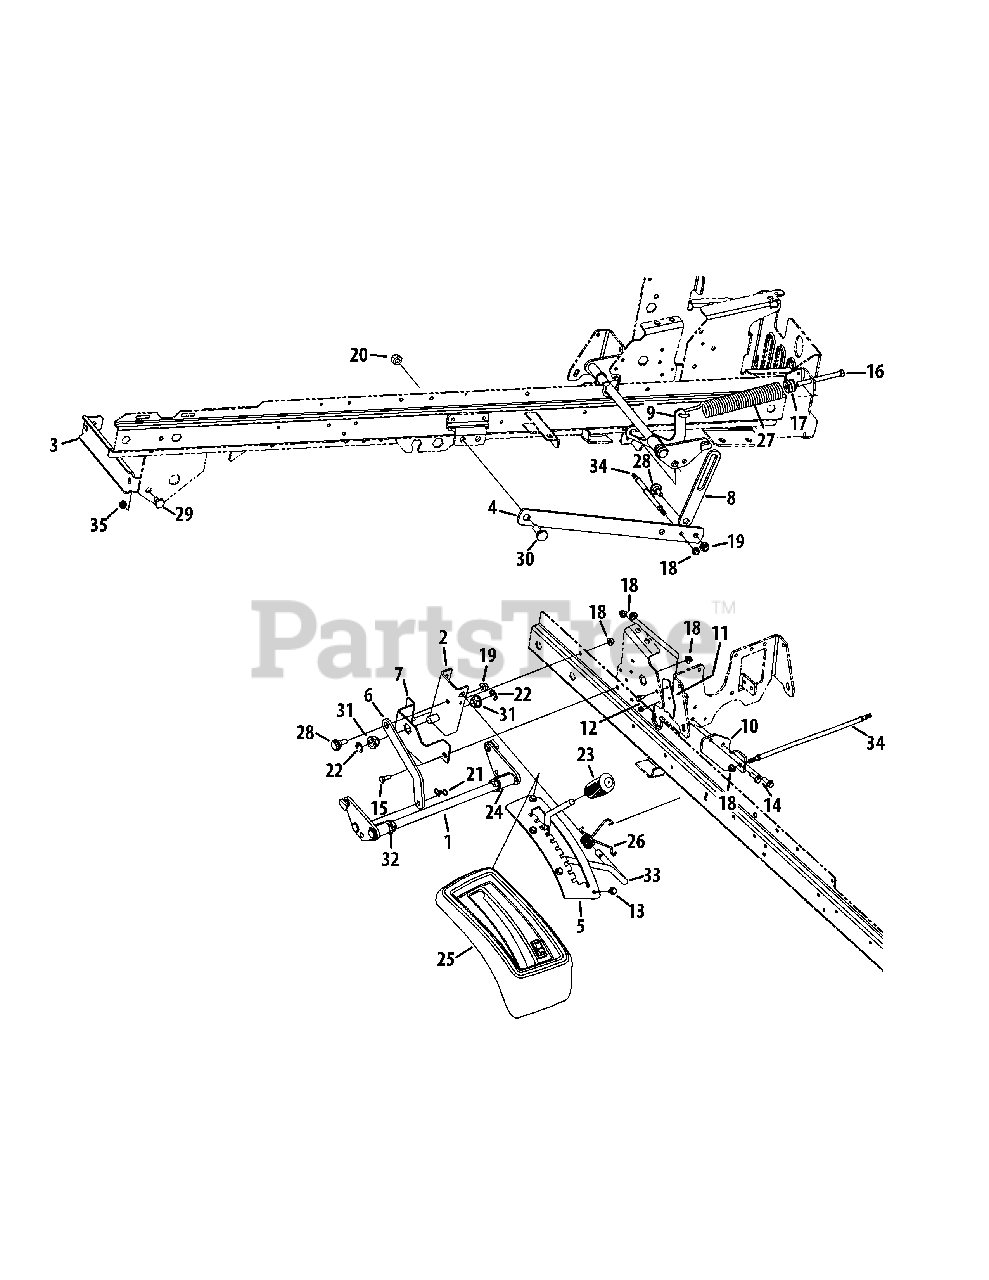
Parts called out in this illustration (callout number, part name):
1	Manual Lift Shaft Assembly
2	Manual Lift Lever Bracket Assembly
3	Front Hanger Bracket
5	Manual Lift Index Bracket
6	Manual Lift Link Plate
7	Manual Lift Lever Mount Bracket
8	Link Lift Plate
9	Extension Spring Plate
10	Sway Bar Mount Bracket
11	Bearing Stop Plate
12	Hex Washer Screw, 1/4-20 x .500
13	Hex Washer Screw, 5/16-18 x .625
14	Hex Washer Screw, 5/16-18 x .875
15	Hex Screw, 5/16-18 x .75
16	Hex Screw, 3/8-16 x 4.25
17	Spring Insert
18	Flange Lock Nut, 5/16-18
19	Flange Lock Nut, 3/8-16
20	Hex Lock Nut, 1/2-13
21	Bow-Tie Cotter Pin
22	E-Ring, .625
25	Lif Manual Cover
26	LH Torsion Spring
27	Extension Spring, 1.485 x 9.68
28	Shoulder Screw, 3/8-16 x .562 x .360
29	Shoulder Screw, 1/2 x .29
30	Shoulder Screw, 1/2-13 x .625 x .36
31	Hex Flange Bearing
32	Hex Flange Bearing
33	Manual Lift Handle Rod
34	Anti-Sway Deck Rod
35	Jam Lock Nut, 3/8-16
